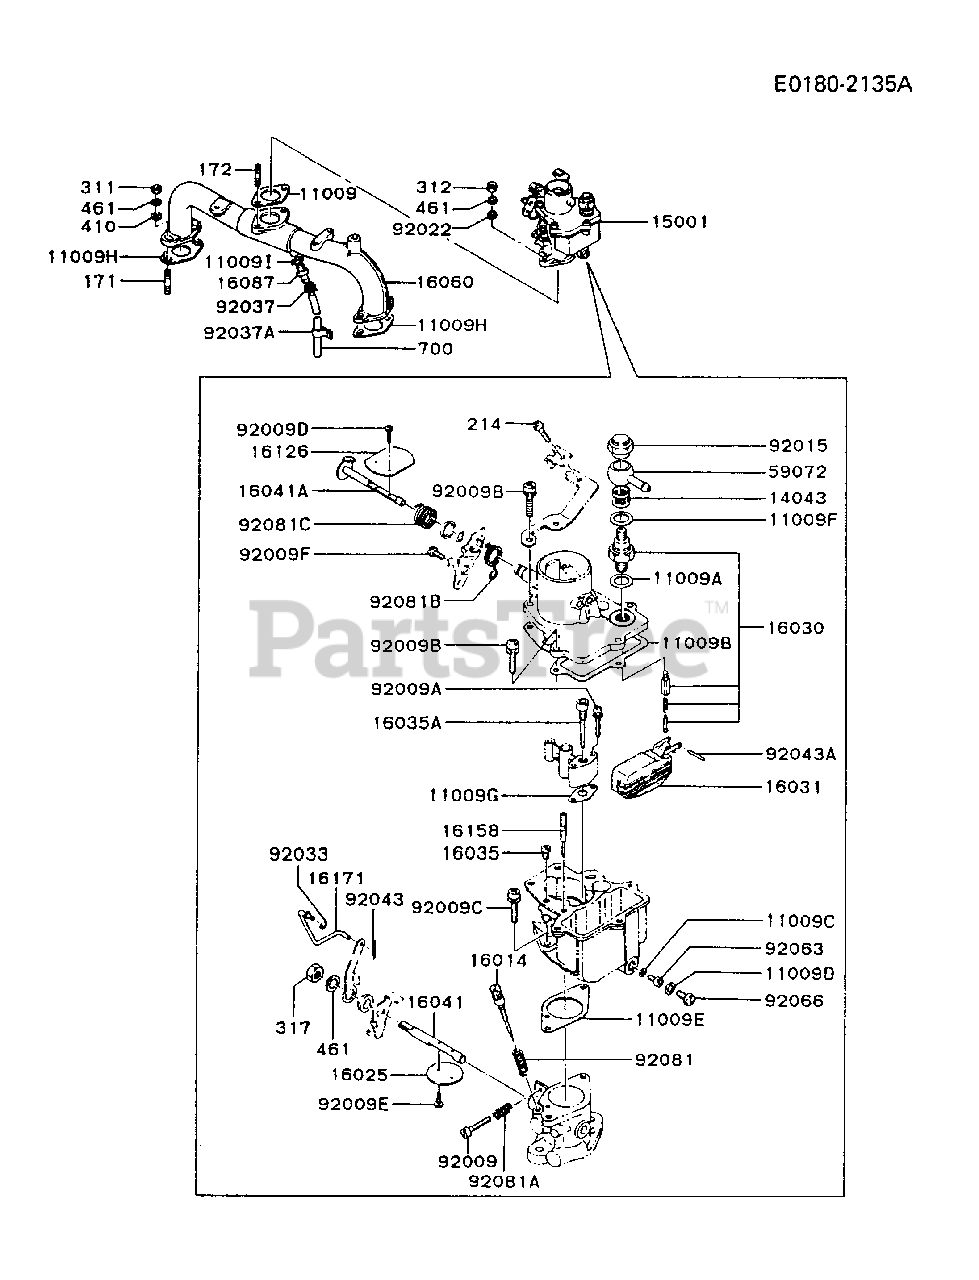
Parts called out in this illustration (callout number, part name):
171	BOLT-STUD
172	BOLT-STUD
214	SCREW-PAN+-
311	NUT-HEX
312	NUT-HEX
317	NUT-HEX-SMALL
410	W-PLAIN-S
461	WASHER-SPRING
700	TUBE-PVC,L=330MM
92063	JET-MAIN,#130
